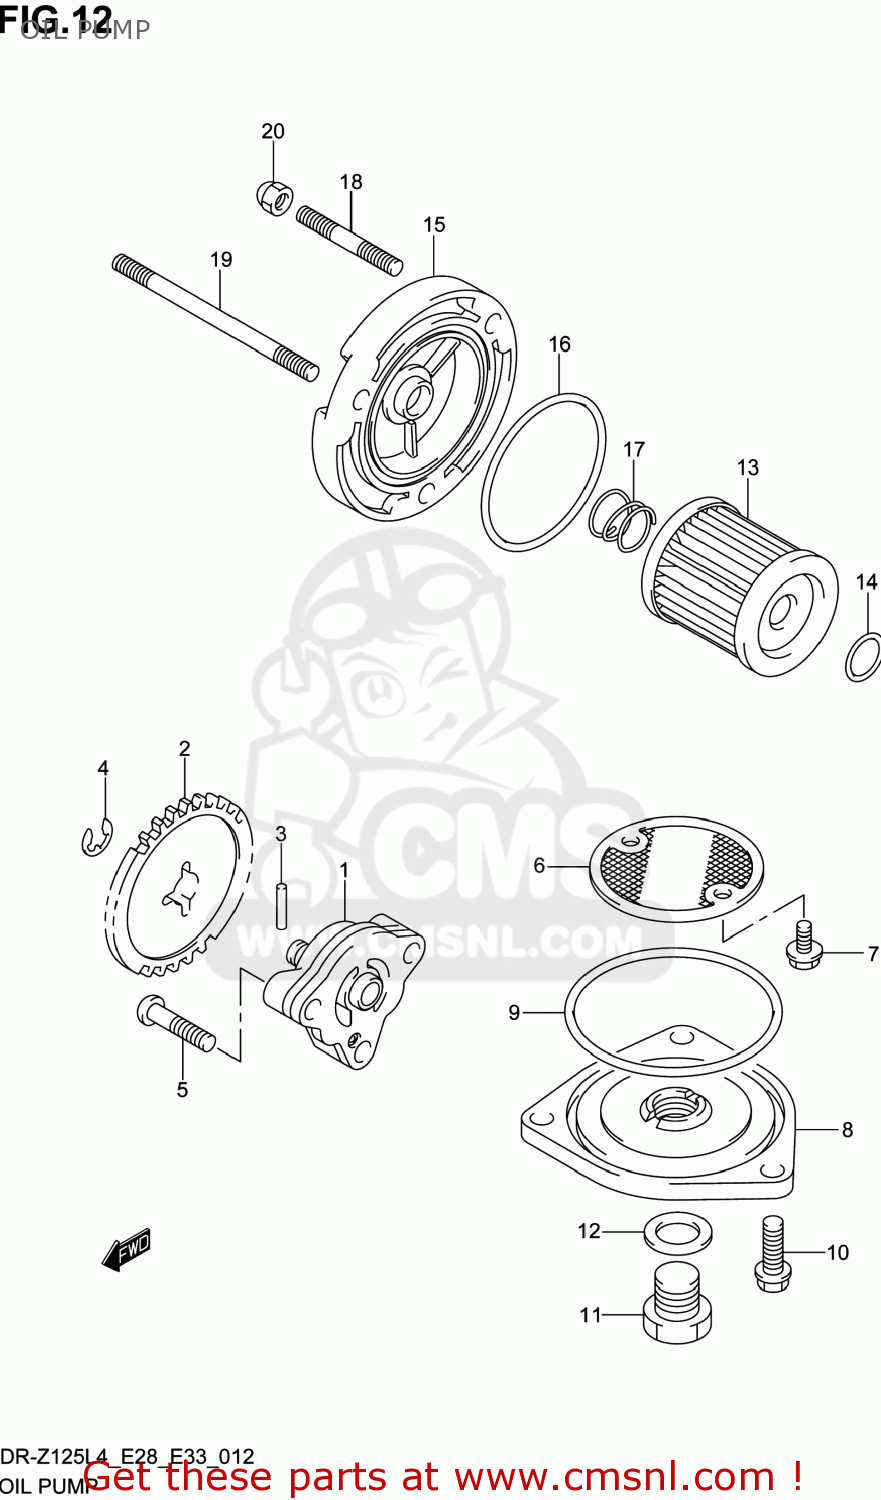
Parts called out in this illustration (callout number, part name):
1	PUMP ASSY,ENGINE OIL
2	GEAR,OIL PUMP DRIVEN
3	PIN(2.5X11.8)
4	E RING
5	SCREW
6	STRAINER,ENGINE OIL
7	SCREW
8	CAP,OIL STRAINER
9	O RING(D:2.4,ID:60.5)
10	BOLT
11	PLUG(14X12)
12	GASKET(13.8X18.8X4.8) (NAS)
13	FILTER ASSY,ENGINE OIL
14	O RING(D:1.9,ID:13)
15	CAP,OIL FILTER
16	O RING(D:2.4,ID:52.6)
17	SPRING
18	BOLT,STUD
19	BOLT,STUD
20	NUT
